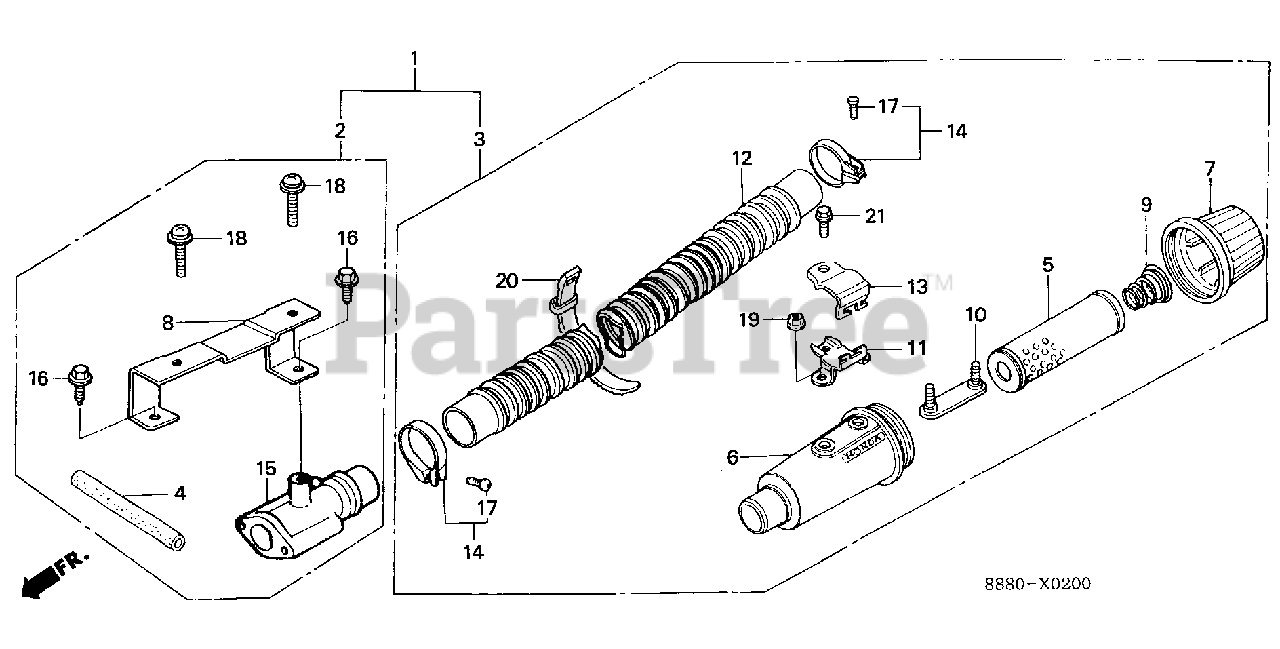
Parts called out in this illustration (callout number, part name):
1	AIR CLEANER KIT, SNORKEL JOINT
2	JOINT KIT, SNORKEL AIR CLEANER
3	AIR CLEANER KIT, SNORKEL
4	TUBE, BREATHER
5	ELEMENT, AIR CLEANER
6	HOUSING, AIR CLEANER
7	CAP, AIR CLEANER
8	STAY, CARBURETOR COVER
9	SPRING, SETTING
10	PLATE, AIR CLEANER SETTING
11	BRACKET A, AIR CLEANER
12	HOSE, AIR CLEANER
13	BRACKET B, AIR CLEANER
14	BAND, AIR CLEANER CONNECTING
15	JOINT, TUBE CONNECTING
16	BOLT, FLANGE (6X12) (CT200)
17	SCREW, PAN (4X25)
18	SCREW-WASHER (6X25)
19	NUT, FLANGE (6MM)
20	BAND B3, WIRE
21	BOLT, FLANGE (6X16)
